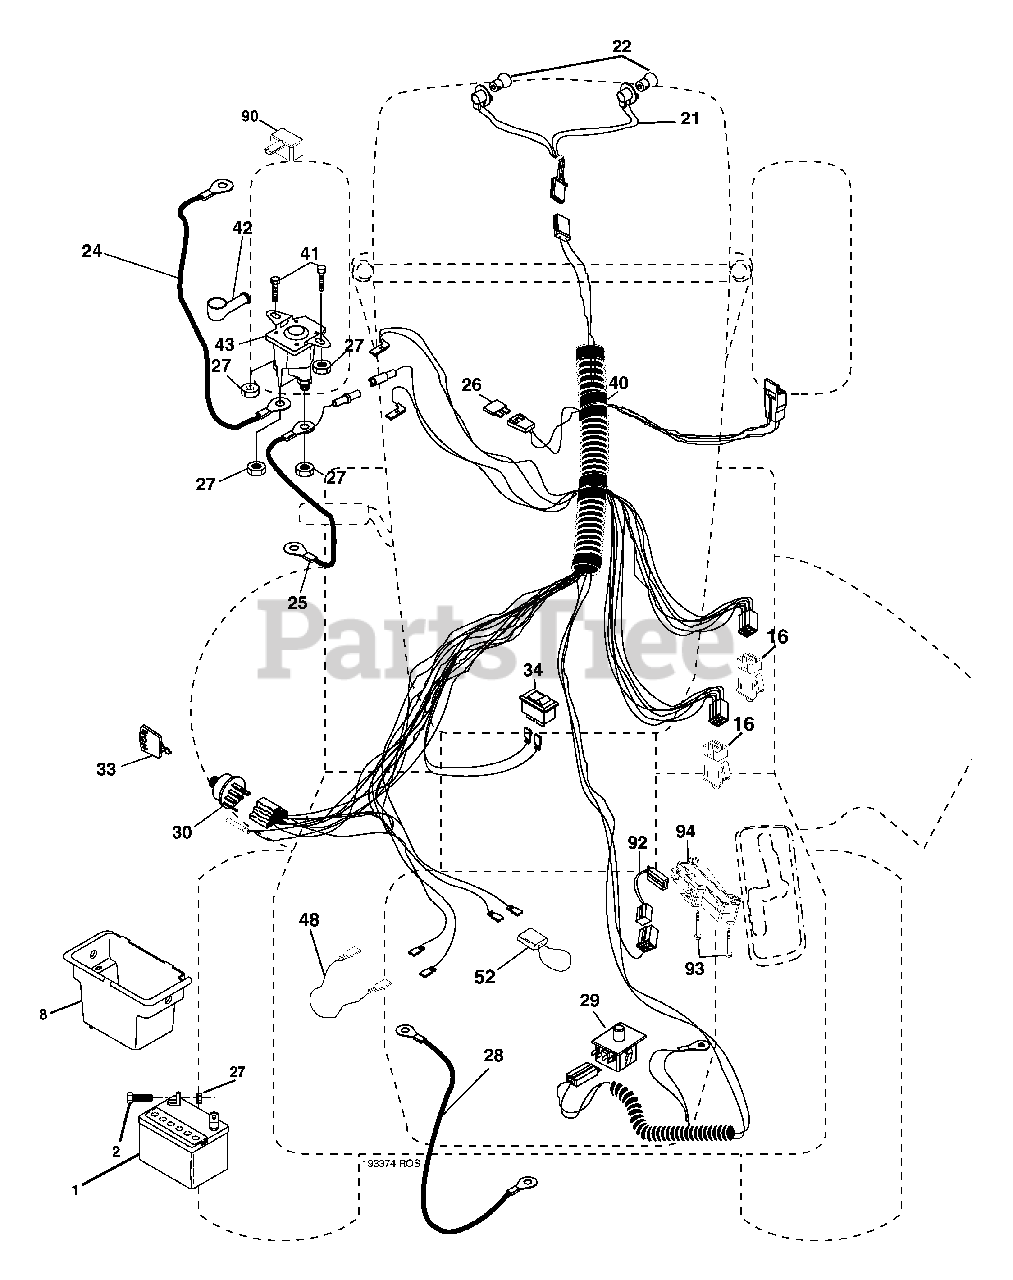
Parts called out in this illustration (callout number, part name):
1	Battery
2	Bolt Hex Hd 1/4-20 unc x 3/4
8	Box Battery
16	Switch Interlock
21	Harness Socket Light
22	Bulb, Light # 1156
24	Cable Battery
25	Cable Battery 6 Ga.Red w/16 wire 44"
26	Fuse
27	Nut Keps Hex 1/4-20 unc
28	Cable Ground 12" Blk 6 Ga.
29	Switch Seat
30	Switch Ign
33	Key Ign Molded Generic
34	Switch Light/Reset
40	Harness Ign
41	Bolt Fin Hex 1/4-20 unc x 1/2
42	Cover Terminal Red
43	Solenoid
48	Adapter Ammeter
52	Protection Loop
90	Cover Terminal
92	Harness Pigtail Reverse Switch
93	Screw Plastic 10-14 x 2.0
94	Modual Reverse ROS
